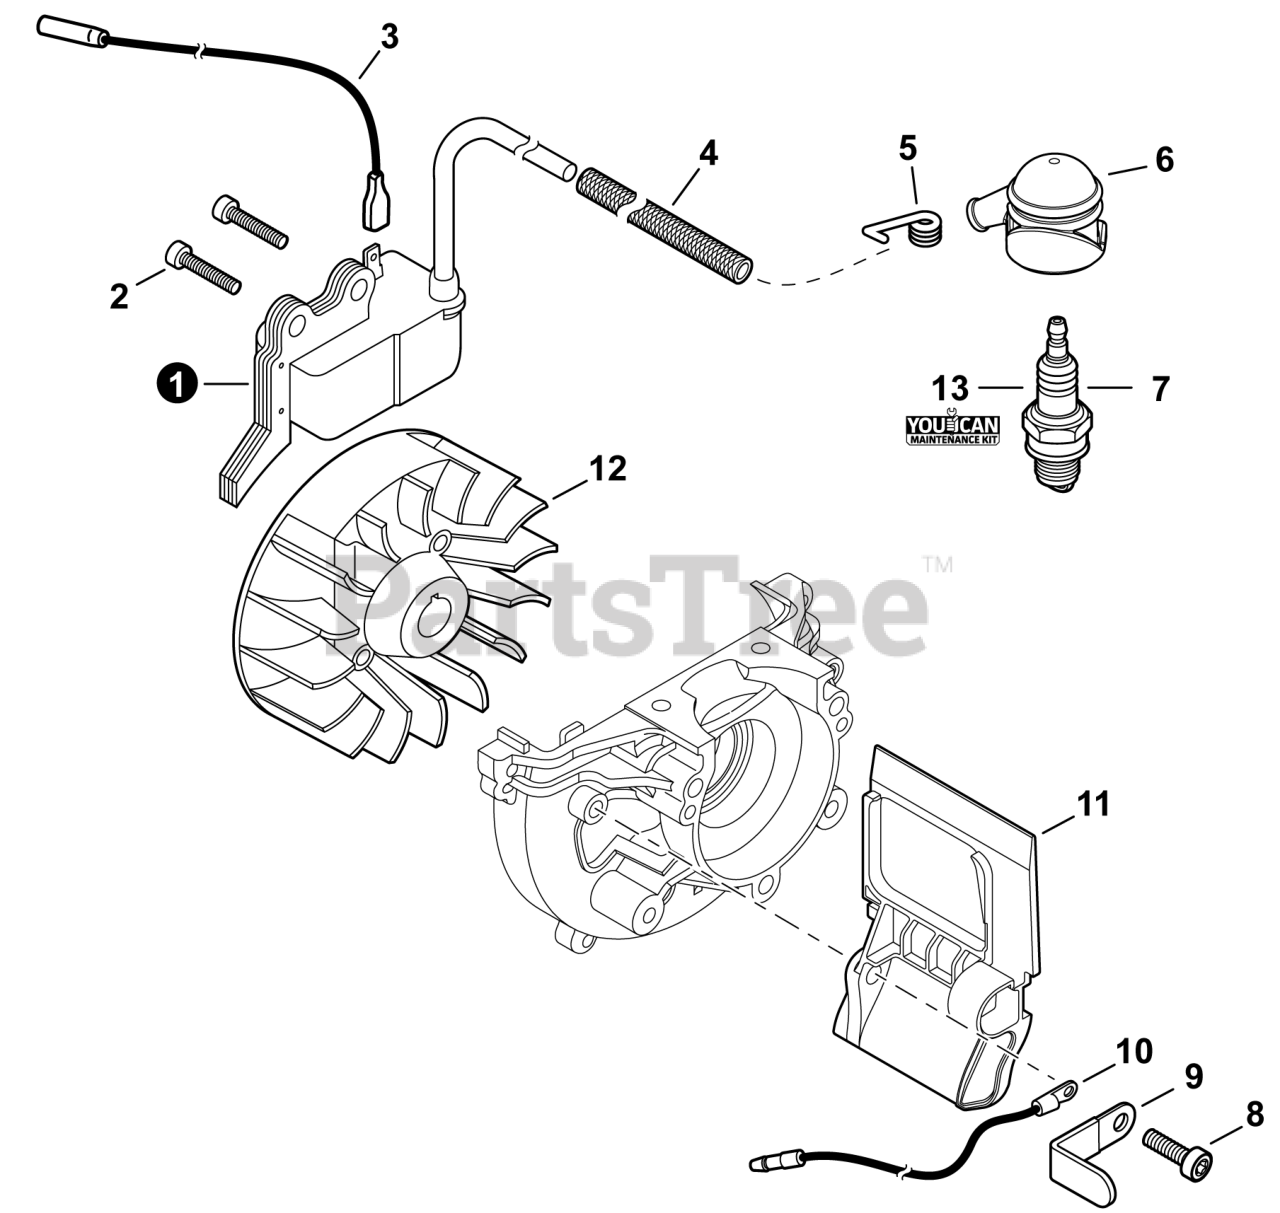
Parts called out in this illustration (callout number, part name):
1	COIL, IGNITION
2	BOLT, TORX 4x20
3	LEAD - IGNITION L= 210
4	TUBE, INSULATOR
5	TERMINAL, SPARK PLUG
6	CAP, SPARK PLUG
7	SPARK PLUG - BPMR8Y
8	BOLT, TORX 5x12
10	LEAD - GROUND L= 115
11	PLATE, INSULATOR
12	FLYWHEEL
13	TUNE-UP KIT - YOUCANT
